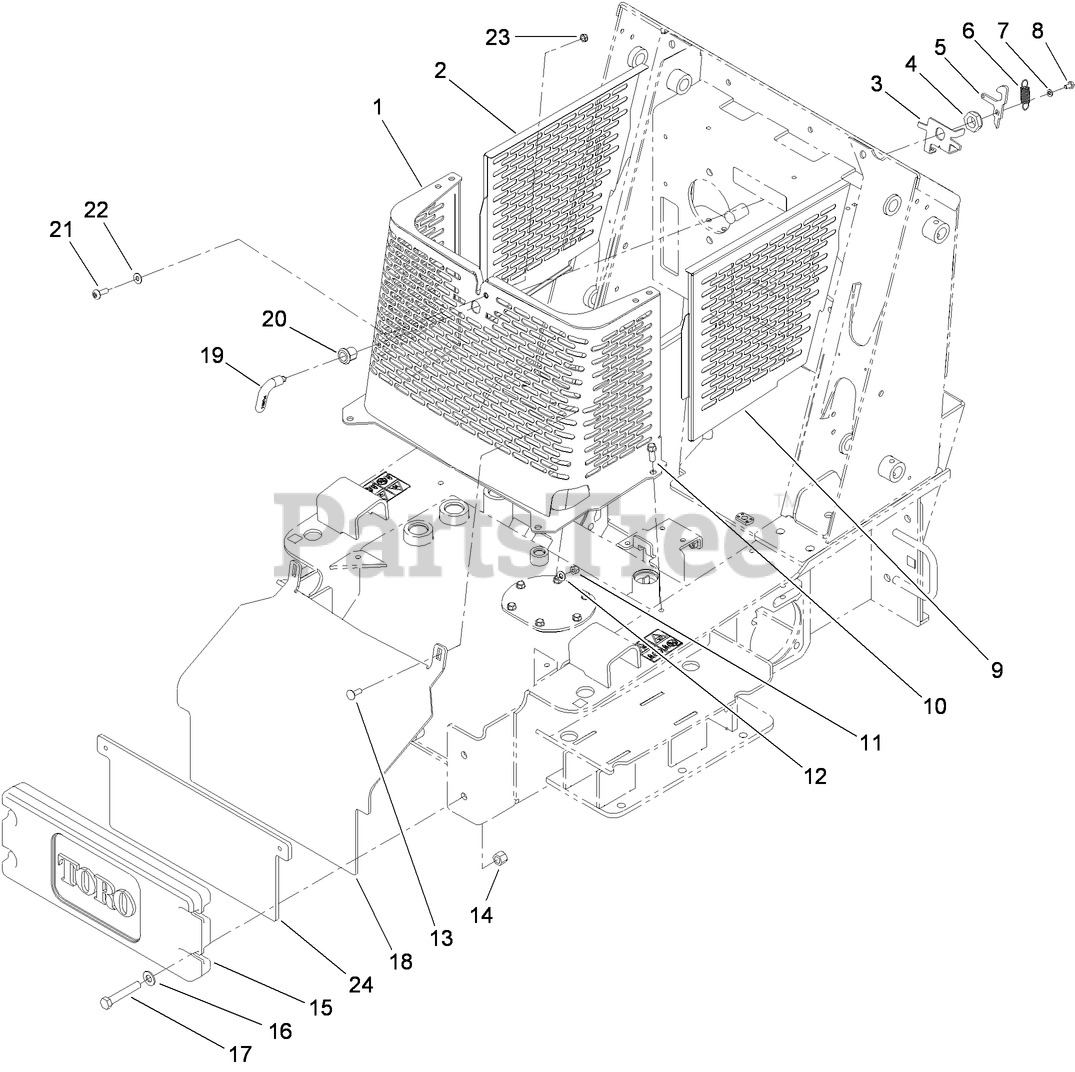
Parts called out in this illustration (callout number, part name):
2	PANEL-SIDE, RH
3	BRACKET-LATCH
4	NUT-LOCK, NI
5	CAM-LATCH
6	SPRING
7	WASHER-LOCK
8	SCREW-HH
9	PANEL-SIDE, LH
10	SCREW-TAPTITE
11	NUT-LOCK, NI
12	WASHER-PLAIN
13	SCREW-CARR
14	NUT-LOCK, NI
15	COUNTERWEIGHT-FRONT
16	WASHER-FLAT
17	SCREW-HH
18	PLATE-FRONT
19	HANDLE-LATCH
20	HOUSING-LATCH
21	SCREW-PTH
22	WASHER-FLAT
23	NUT-LOCK, NI
24	PLATE-COUNTERWEIGHT
